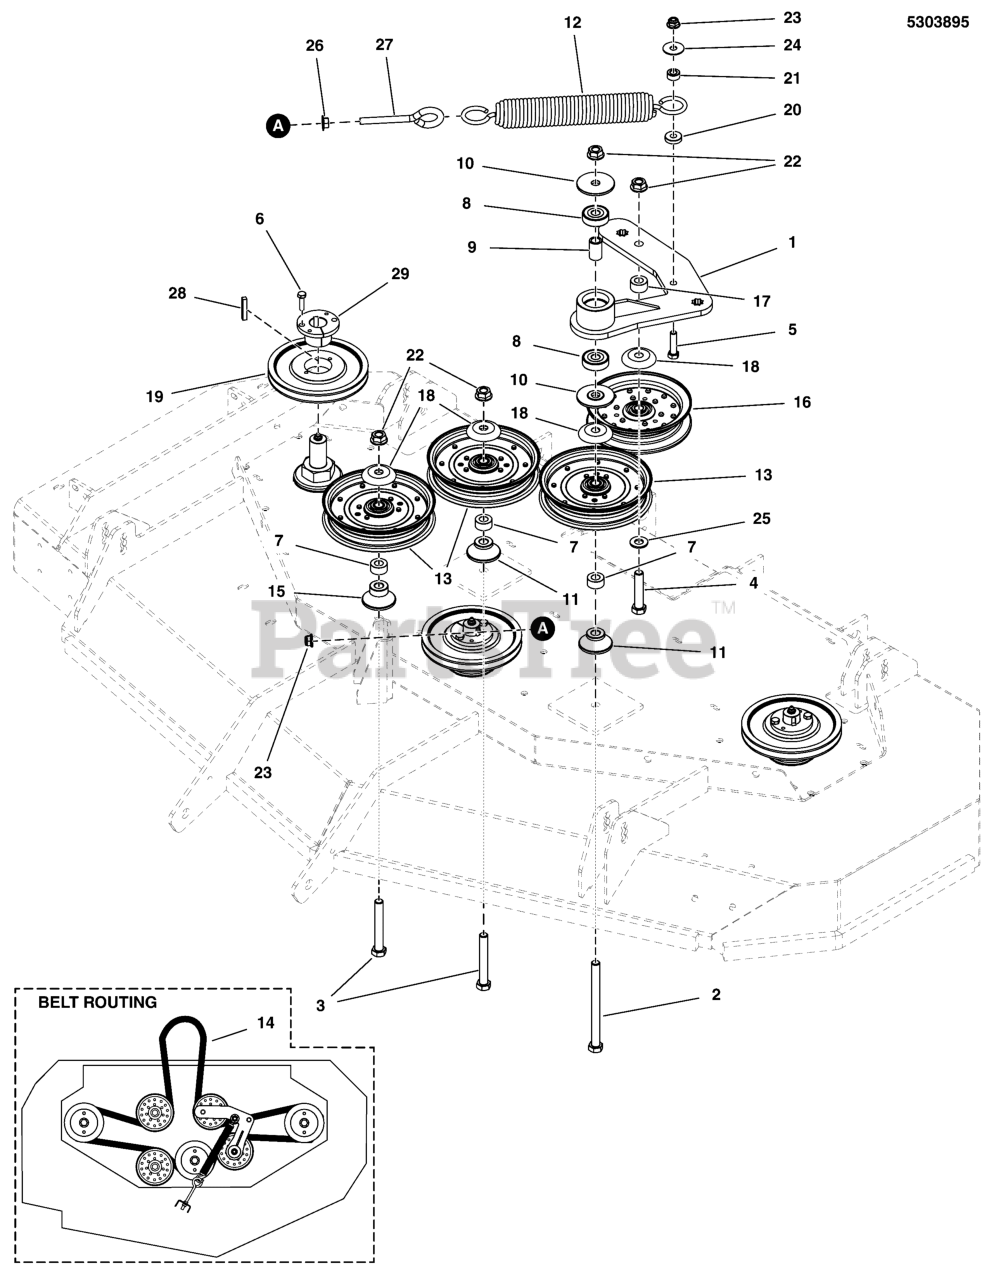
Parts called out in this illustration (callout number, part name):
1	WELD, IDLER ARM - BLK
2	BOLT, 1/2-13 X 6 GD5 CZ
3	BOLT, 1/2-13 X 3-1/2, HEX HD, GD5, CZ (SV)
4	BOLT, 1/2-13 X 2-1/2" GD5 CZ
5	BOLT, 3/8-16 X 1-1/2" GD5 CZ
6	BOLT, 1/4-20 X 1" GD5 CZ
7	SPACER, .52 X 1.00 X .50, CZ
8	BEARING, 6203-1/2", SEALED
9	SPACER, .51 X .75 X 1.22, PM CZ
10	SPACER, IDLER ARM, 1/2 X 2.25
11	IDLER MOUNT, .88 HIGH
12	SPRING, EXT, 1.5ODX12.25X.234WIRE BLK
14	BELT, 5V, 178.25"EL, ARAMID, WRAP RC
15	IDLER MOUNT
17	SPACER, .52 X 1.00 X .56, PM, CZ
18	SHIELD, PULLEY BEARING, CZ
19	PULLEY, SPLIT STEEL, 6.432"OB, HQ BORE
20	SPACER, .39 X 1.00 X .25, PM, CZ
21	SPACER, .39 X .75 X .38, PM, CZ
22	NUT, Hex Flange, Nylock, 1/2-13
23	NUT, 3/8-16 HEX NYLOCK FLANGE
24	WASHER-3/8 FENDER
25	WASHER, 1/2 SAE
26	NUT, 3/8-16 HEX SERRATED FLANGE
27	EYE BOLT, 3/8-16 X 5, 2.88THRD, 1EYE, CZ
28	KEY 1/4 SQ X 1 1/2 LONG
29	BUSHING, TAPERED HUB
